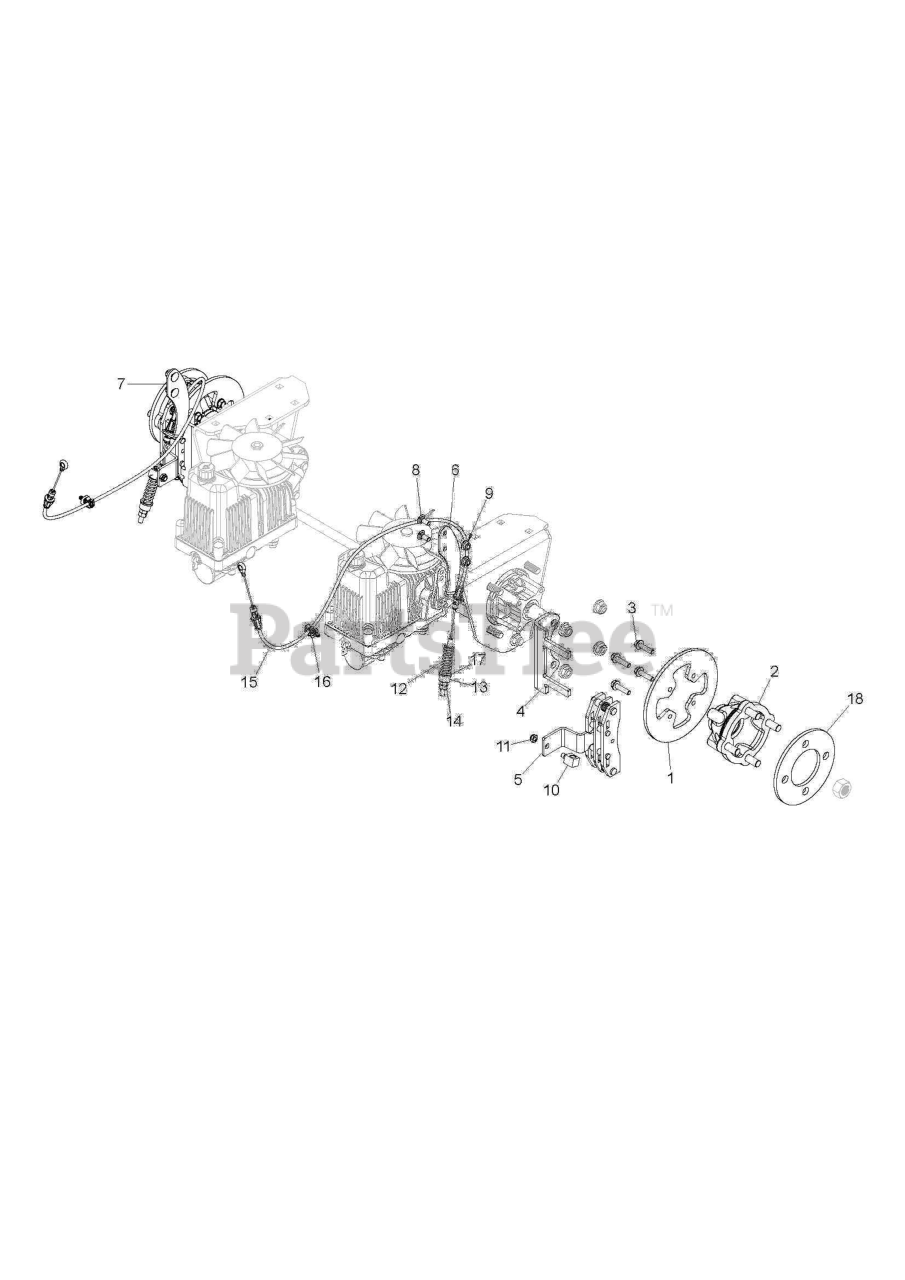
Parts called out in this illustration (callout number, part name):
2	Hubs
8	GSPW Bolts
9	NUT HEXAGON FLANGE 5/16-18 ST
16	CABLE, 1/4 BLACK FIR TREE
18	WHEEL SPACER ZT-3400 CARLISLE
